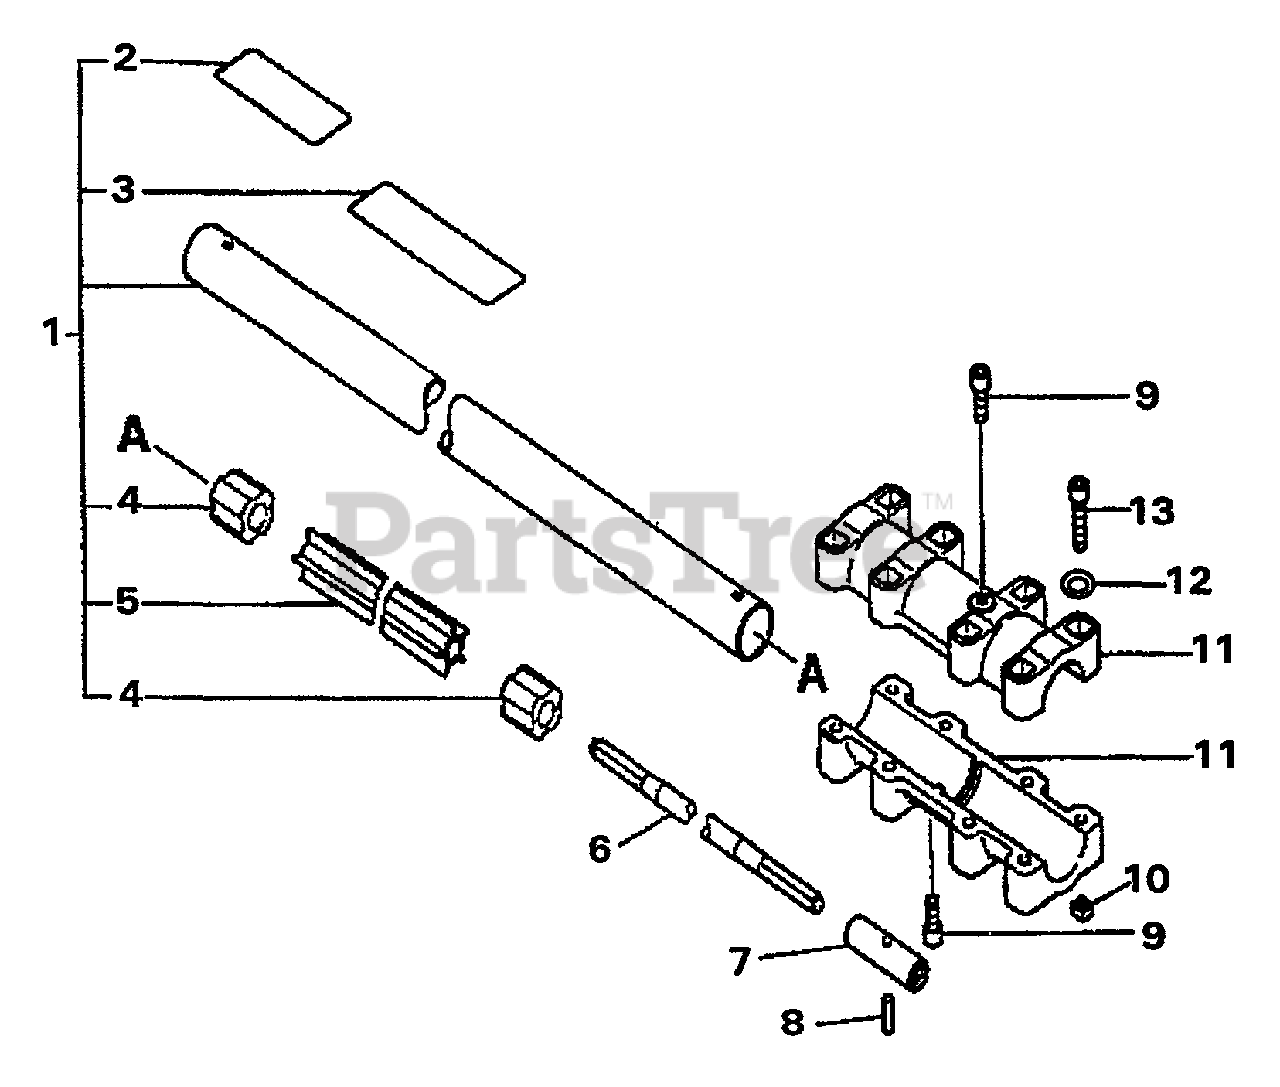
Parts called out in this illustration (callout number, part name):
1	MAIN PIPE ASSY
2	LABEL - CAUTION
3	LABEL - CAUTION
5	LINER - FLEXIBLE
6	DRIVESHAFT - FLEXIBLE
7	CONNECTOR, SHAFT
8	PIN - SPRING - 1/8 X 1/2
9	SCREW - 5X14
10	NUT - 5 -- SQUARE
11	HOLDER
12	LOCKWASHER - 5
13	SCREW - 5X25
